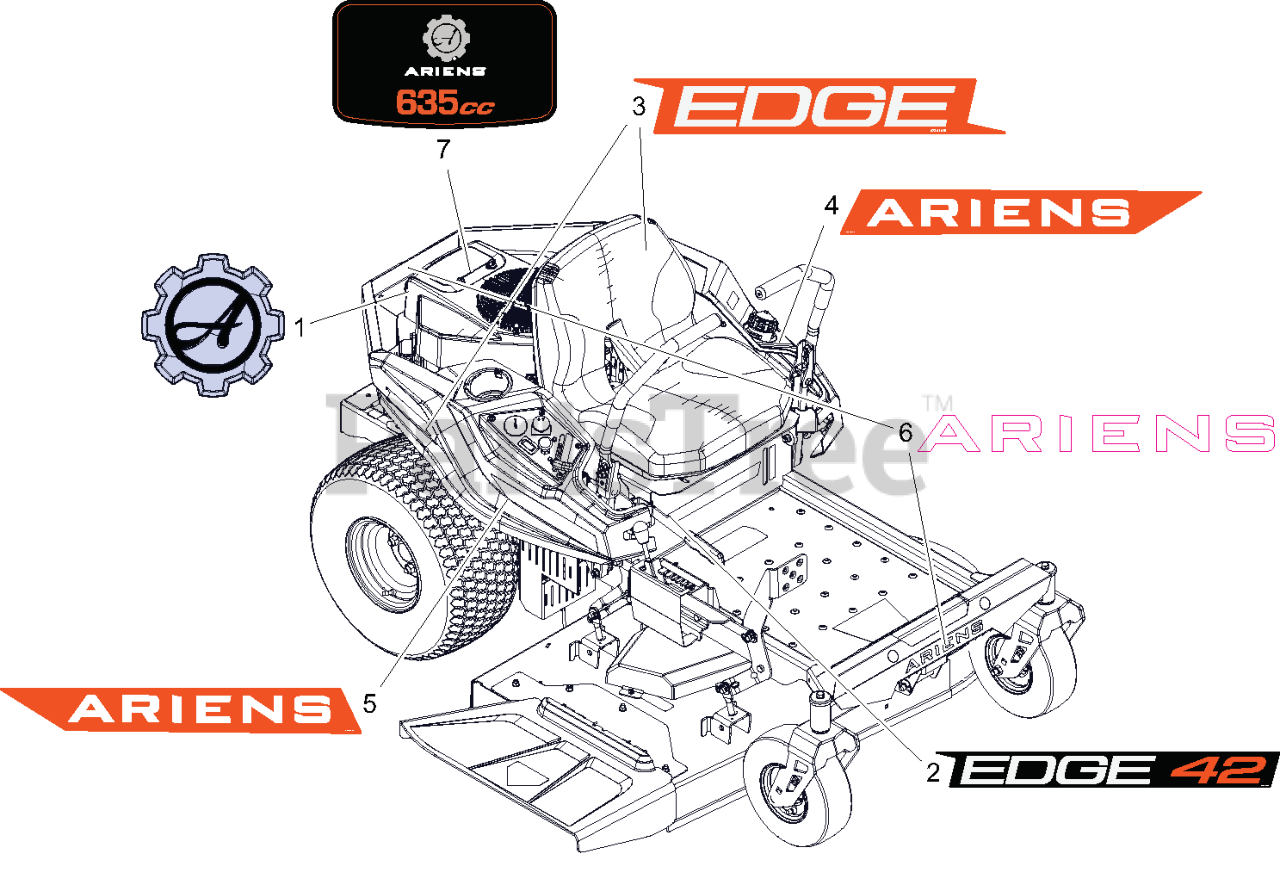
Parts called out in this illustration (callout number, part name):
1	DECAL, ARIENS - GEAR BADGE
2	DECAL, EDGE 42 - KICKPLATE
3	DECAL, EDGE FENDER
4	DECAL, ARIENS FENDER LH
5	DECAL, ARIENS FENDER RH
6	DECAL - ARIENS 9.625"
7	DECAL, ENGINE 635 CC
